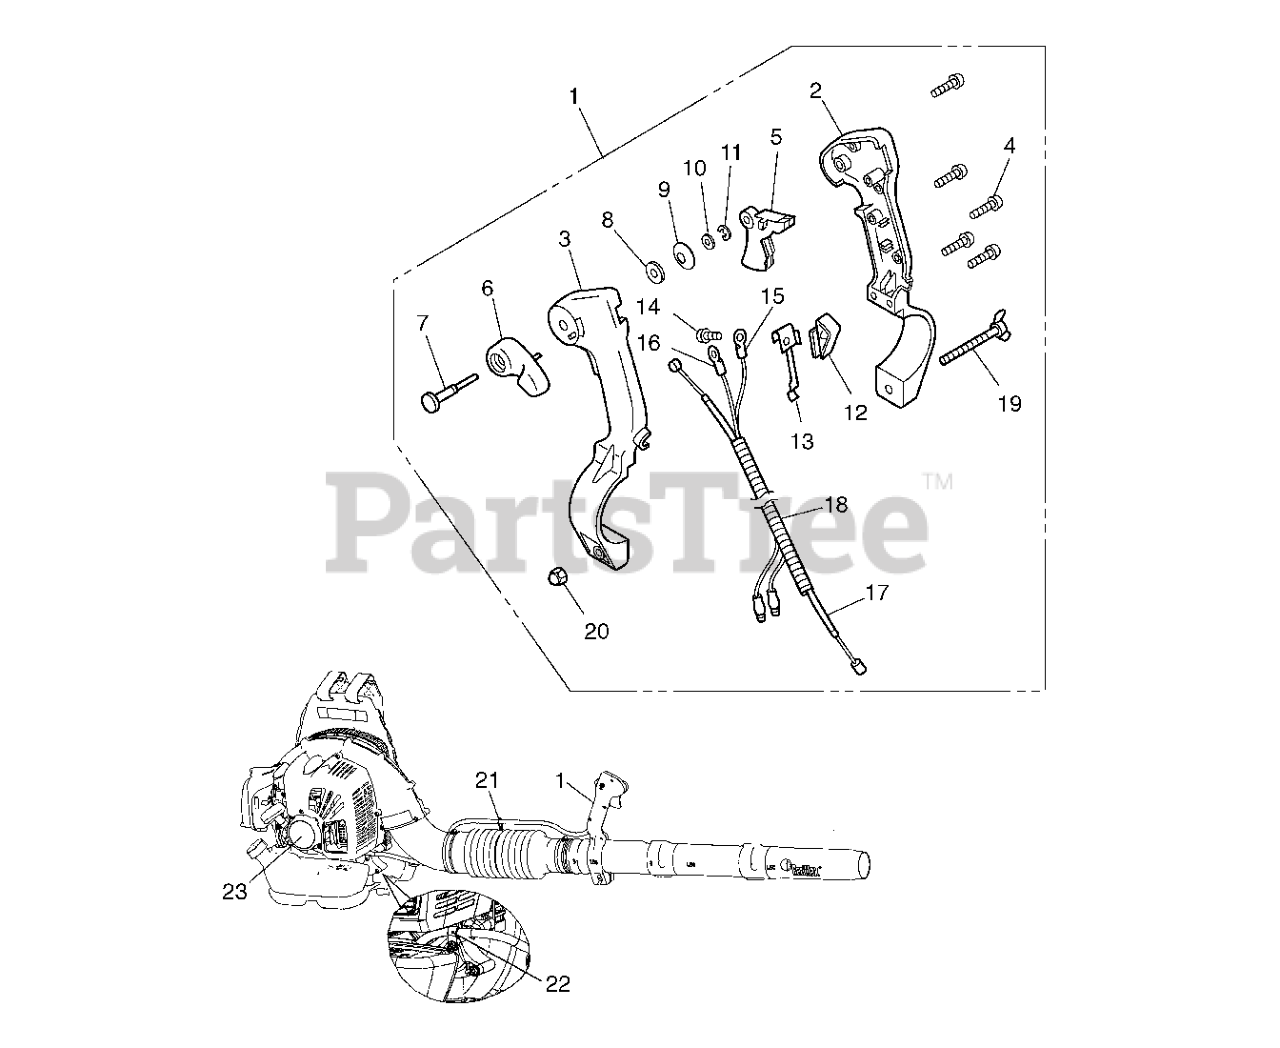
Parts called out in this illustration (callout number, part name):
1	LEVER(R)SET
4	SCREW 4X14(T)
5	LEVER THROTTLE
6	RP_LEVER (RPLS T402325430)
7	SHAFT
8	WASHER(T)
9	RP_SPRING WASHER
10	WASHER
11	RP_CLIP(T)
12	SWTICH (T)
13	SPRING (RPLS T402325720)
14	RP_SCREW 4X10(T)
15	CORD, RED
16	CORD, RED
19	BOLT WING
23	RECOIL DECAL
